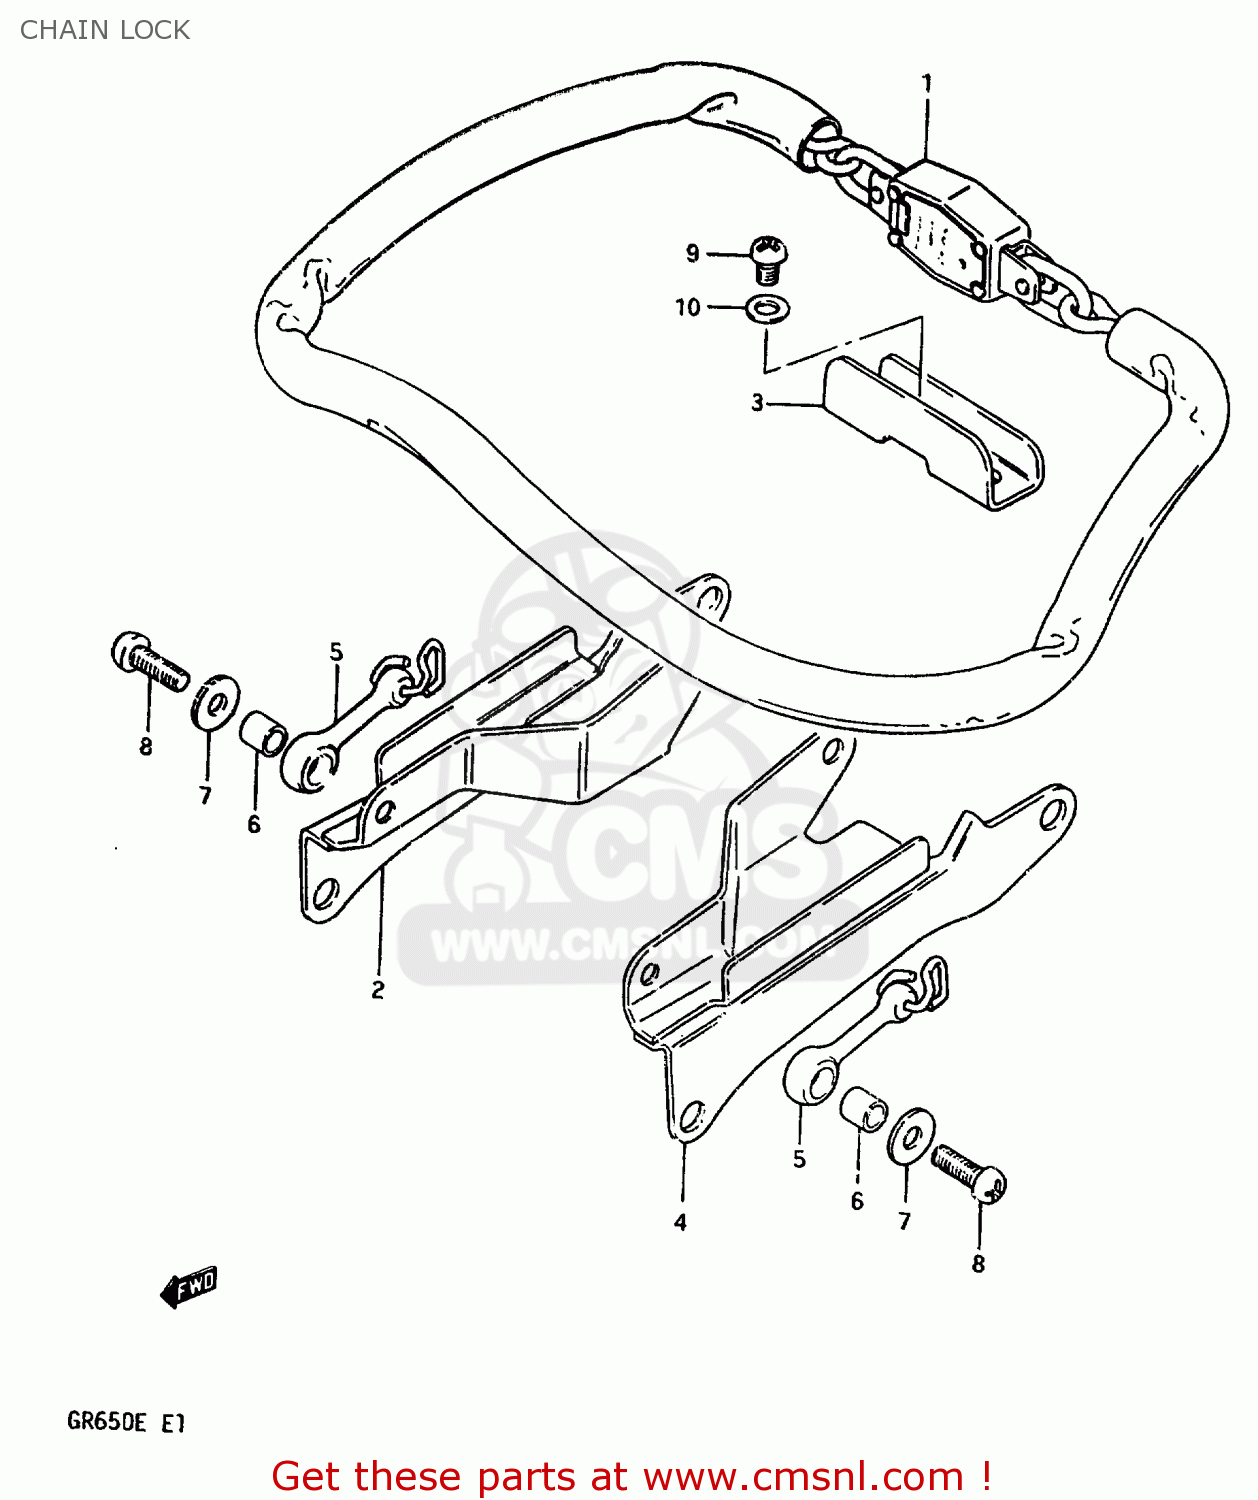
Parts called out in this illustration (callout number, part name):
1	CHAIN LOCK ASSY
2	HOLDER, RH
3	HOLDER, REAR
4	HOLDER, LH
5	BAND
6	SPACER (6.1X9X9)
7	WASHER
8	SCREW
9	SCREW
10	WASHER
